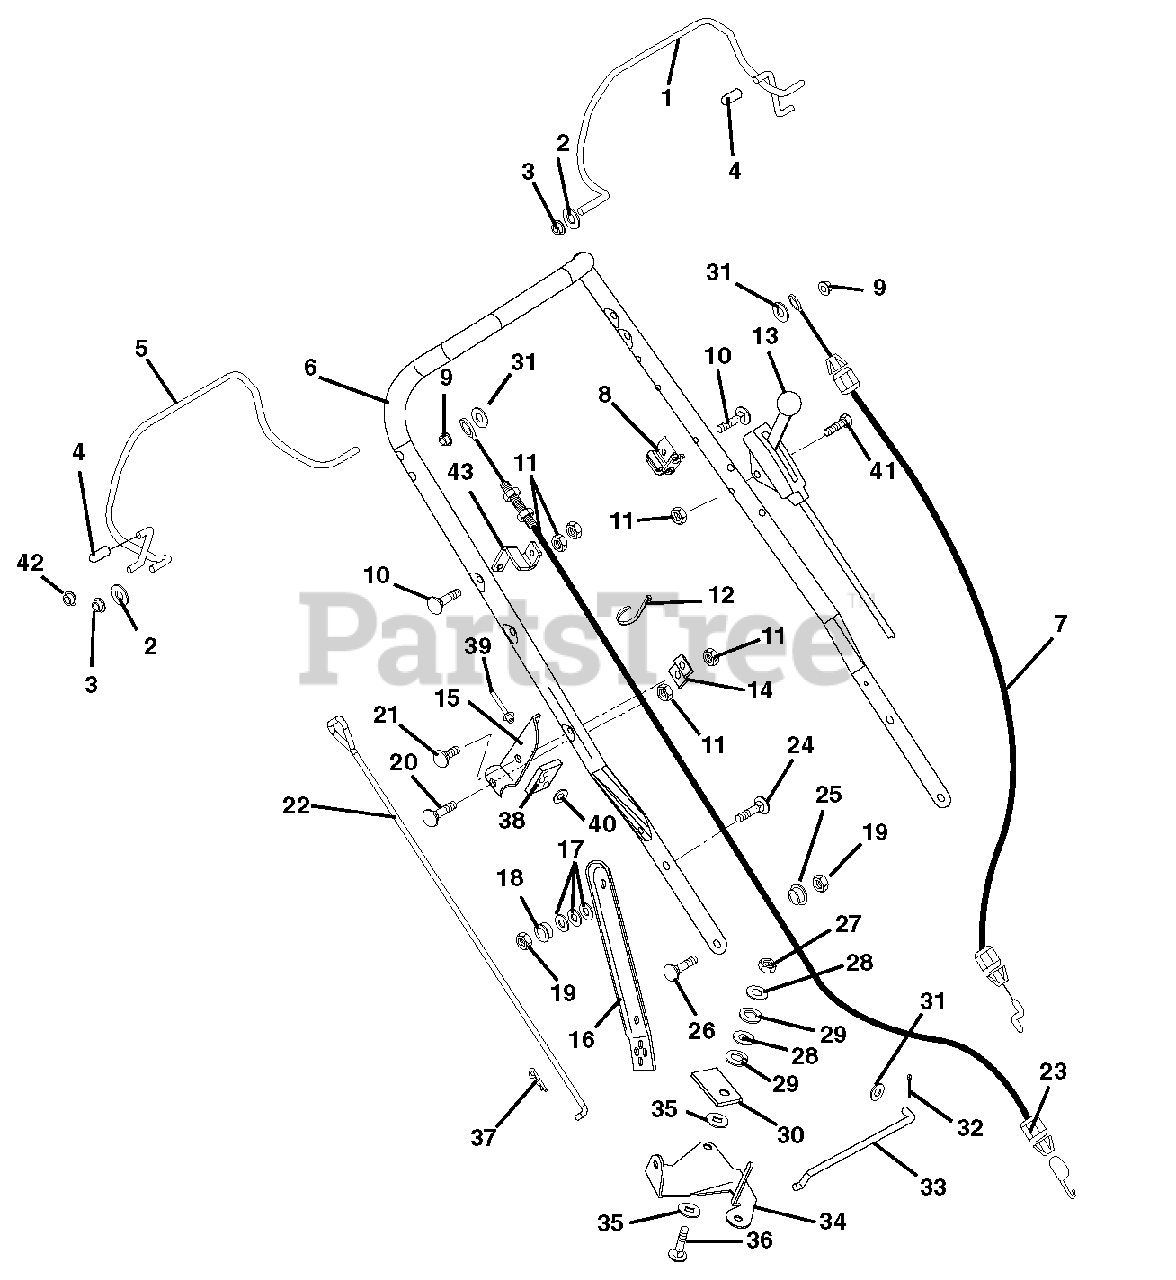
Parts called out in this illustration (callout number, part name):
1	Bail, Engine
2	Washer, Flat Steel .32 x .44 x .44 x .56 (911196, 197)
3	Bushing, Flange .325 x .688 x .560 (911196, 197)
4	Cap, Vinyl .25 I.D. (911196, 197)
5	Traction Bail (911196, 197)
6	Handlebar
7	Cable, OPC (911171)
8	Cable, Anchor
9	Push Nut, .25
10	Bolt, Round Head Square Neck .25-20 x 1.25 (911196, 197)
11	Nut, Locking Center .25-20 (911196, 197)
12	Cable Tie
13	Cable, Lockout Control (911197)
14	Brace, Speed Control (911196, 197)
15	Bracket, Speed Control (911196, 197)
16	Link, Handlebar Adjuster Left Hand
17	Washer, Bellville Spring
18	Bushing, Flange .325 x .50 x .513 x .875
19	Nut, Locking Center .31-18
20	Bolt, Round Head Square Neck .25-20 x 1.38
21	Bolt, Round Head Square Neck .25-20 x .50 Grade
22	Rod, Speed Control (911196, 197)
23	Traction Cable (911196, 197)
24	Bolt, Round Head Square Neck .31-18 x 1.00 Grade 5
25	Shoulder Spacer
26	Bolt, Round Head Square Neck .31-18 x .75 Grade 5
27	Nut, Locking Center .38-16 (911196, 197)
28	Washer, Flat Steel .406 x .812 x .065 (911196, 197)
29	Washer, Lock .375 x .115 Heavy (911196, 197)
30	Pressure Flange (911196, 197)
31	Washer, Flat Steel .281 x .62 x .065 (911196, 197)
32	Pin, Cotter .06 x .50 (911196, 197)
33	Shift Link (911196, 197)
34	Bell Crank, Speed Control (911196, 197)
35	Friction Washer (911196, 197)
36	Bolt, Round Head Square Neck .38-16 x 1.25 (911196, 197)
37	Pin, Hair Internal .08 x .18 x 1.18 (911196, 197)
38	Support Pad
39	Rivet .187 x .575
40	Washer, Flat Steel .219 x .50 x .049
41	Bolt, Round Head Square Neck .25-20 x 2.00 Grade 5 (911196, 197)
42	Nut, Push .312
43	Anchor, Cable (911196, 197)
